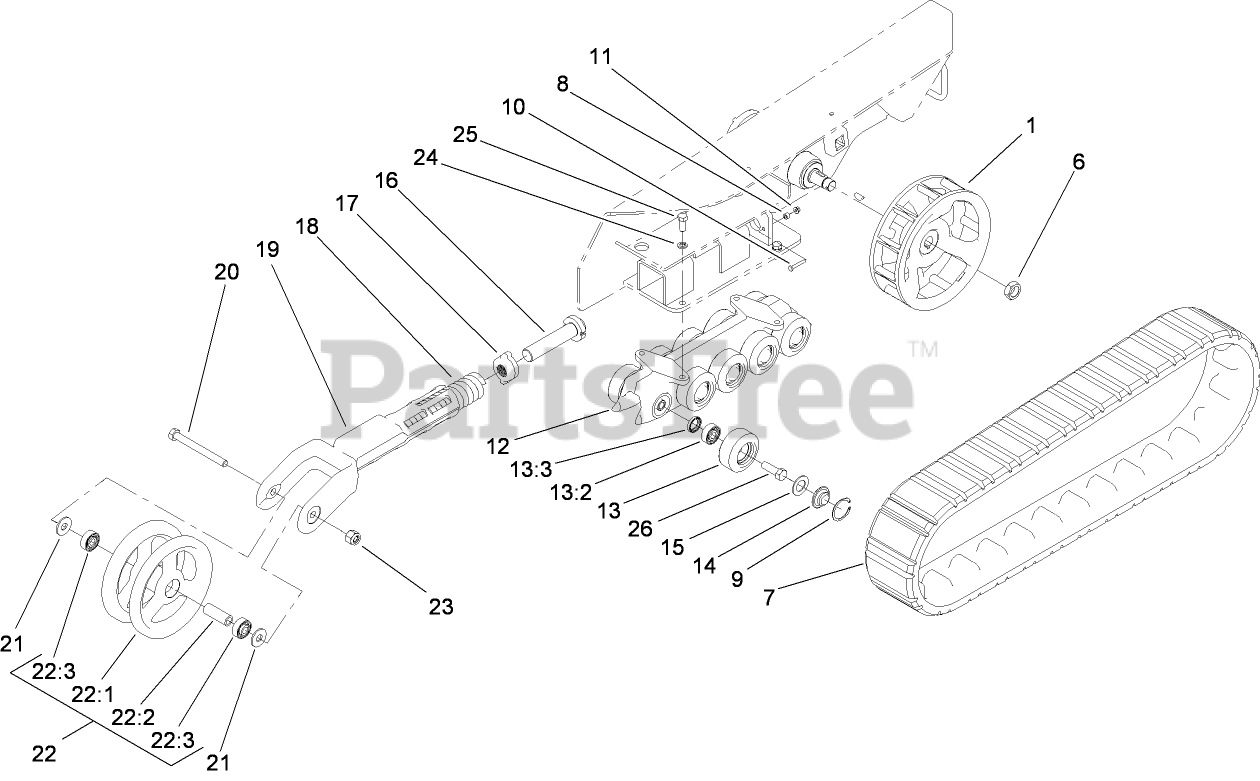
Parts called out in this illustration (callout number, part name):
1	WHEEL-DRIVE
6	NUT-LOCK
7	TRACK
8	SPACER
9	RING-SNAP, INTERNAL
10	SCREW-HH
11	NUT-HHF
12	GUIDE-TRACK
13	Road Wheel ASM
13:2	BEARING
13:3	SEAL-OIL
14	CAP-WHEEL, BEARING
15	Gasket-Bogie
16	BOLT-TENSIONER
17	BLOCK-TENSIONER
18	SPRING-COMPRESSION
19	ARM-TENSIONER
20	SCREW-HH
21	WASHER-FLAT
22	TENSIONER WHEEL ASM
22:1	WHEEL-TENSIONER
22:2	SPACER-WHEEL, TENSIONER
22:3	BEARING
23	NUT-HEX
24	WASHER-LOCK
25	SCREW-HH
26	SCREW-HH
